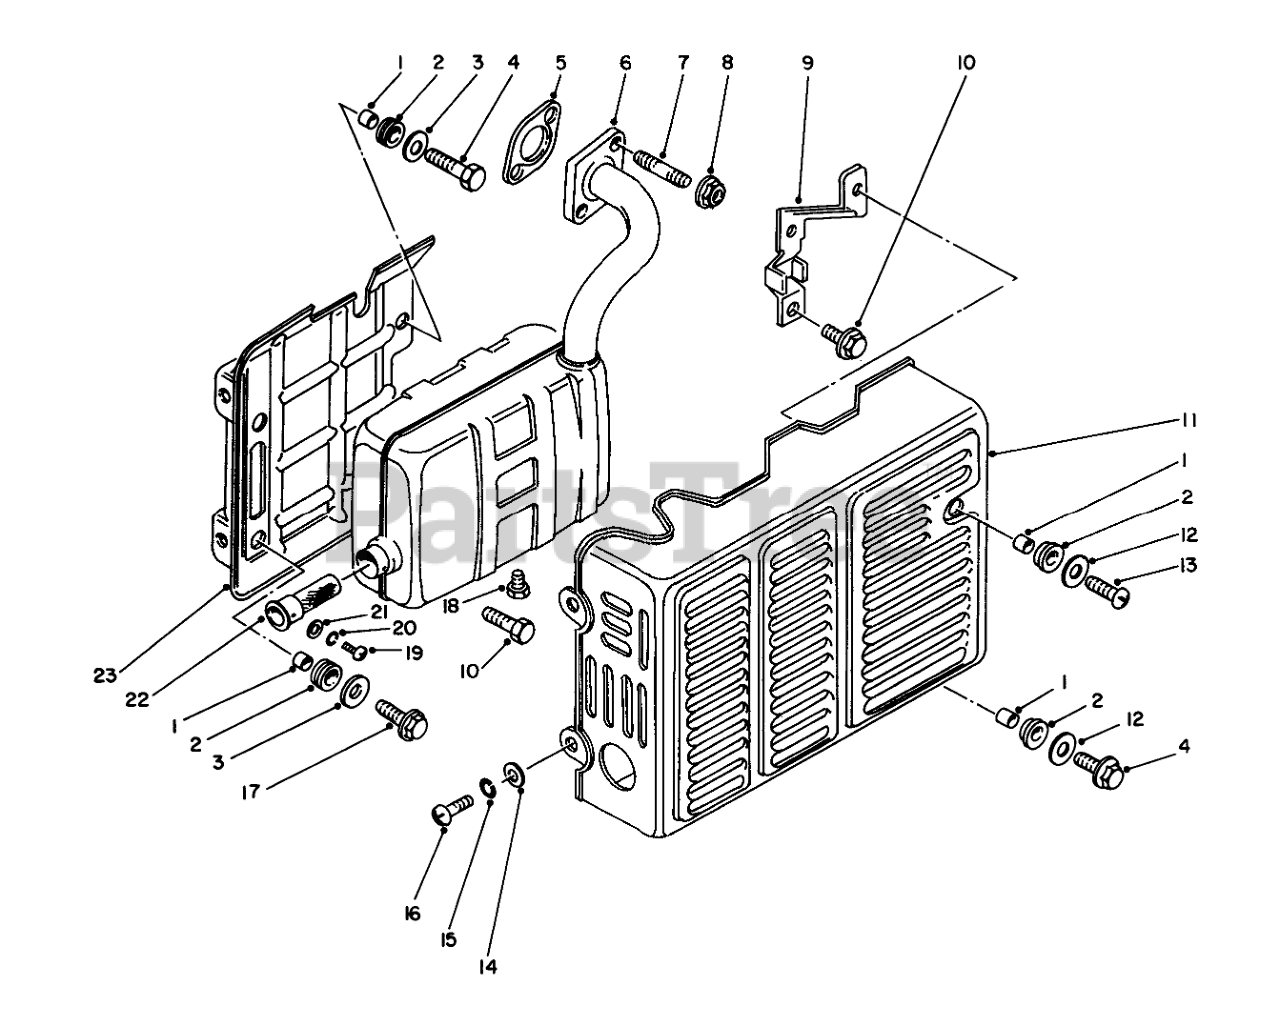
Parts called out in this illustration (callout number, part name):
1	Spacer
2	Cushion
3	Washer
5	Gasket
6	Muffler
7	Bolt-Stud
9	Bracket-Governor Spring
11	COVER
12	Washer
13	Screw
14	Washer
15	Washer-Lock
16	SCREW
18	Plug-Drain
20	Lockwasher
21	Washer
22	Spark Arrestor
23	Cover-Rear
